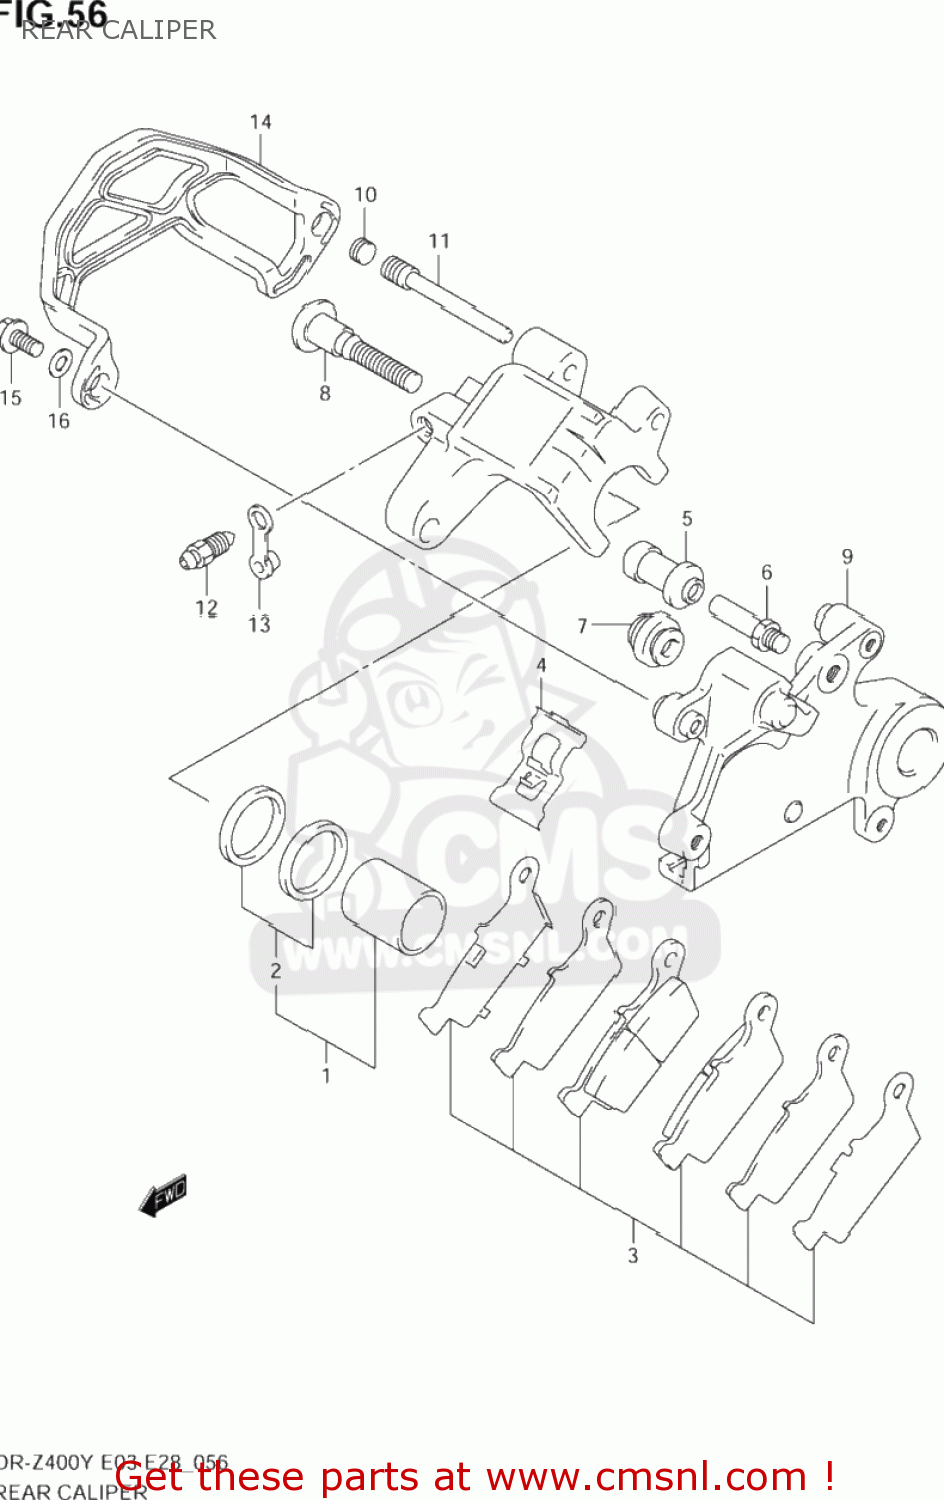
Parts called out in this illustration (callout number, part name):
1	PISTON SET
2	SEAL SET,PISTON
3	PAD & RETAINER SET
4	SPRING,PAD
5	BOOT
6	BOLT
7	BOOT
8	PIN,BOLT
9	BRACKET
10	PLUG,PIN
11	PIN,HANGER
12	BLEEDER
13	CAP,BLEEDER
14	GUARD,RR CALIPER
15	BOLT
16	WASHER
